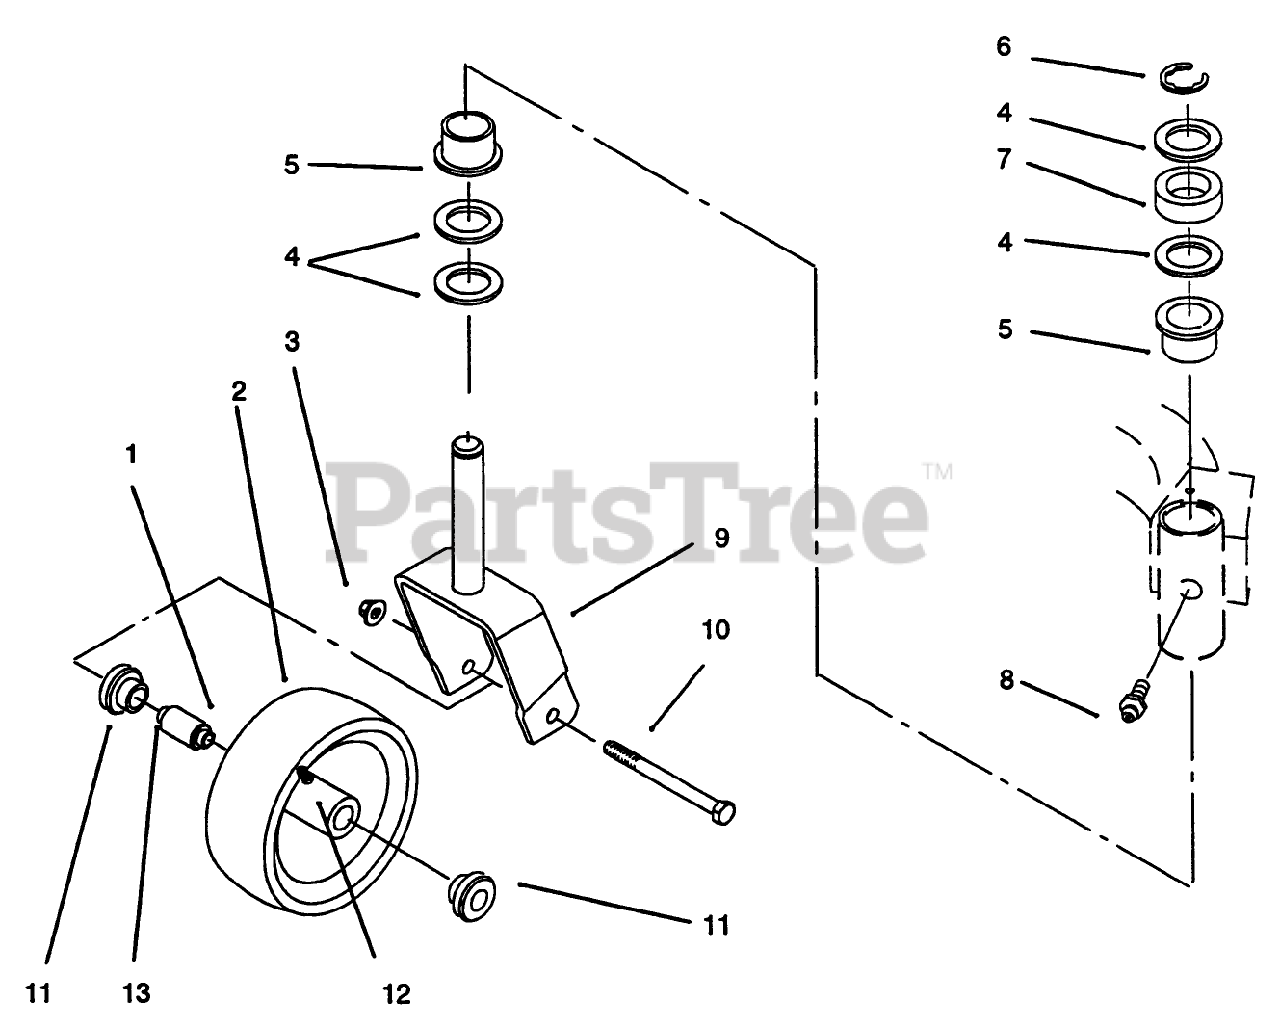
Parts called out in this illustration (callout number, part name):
1	BEARING
2	Wheel & Tire Assembly (Incl. Ref. #1 & 11-13)
3	NUT-HEX
4	WASHER-THRUST
5	Bushing
6	RING-RETAINING
7	SPACER
8	FITTING-GREASE
9	Fork-Castor
10	SCREW-HH
11	BEARING-OUTSIDE
12	FITTING-GREASE, 90 DEG
13	SPANNER
